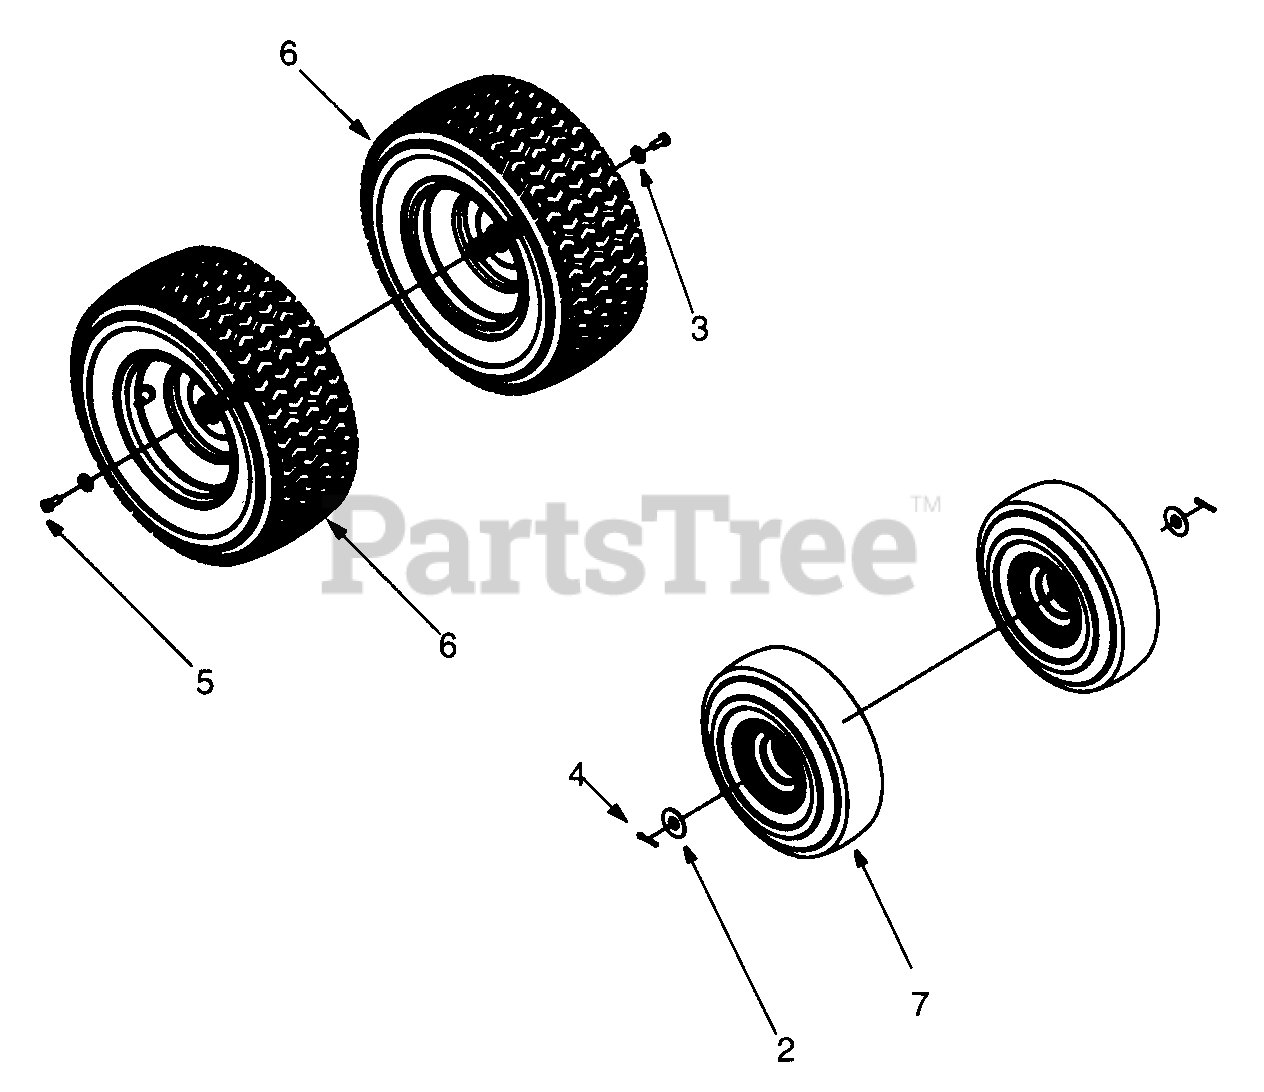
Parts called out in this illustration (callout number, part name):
2	Flat Washer .635 x 1.589 x .060
3	Bell Washer .345I.D. x .88 O.D. x .06
4	Cotter Pin
5	Hex Screw 5/16-24 x .75
